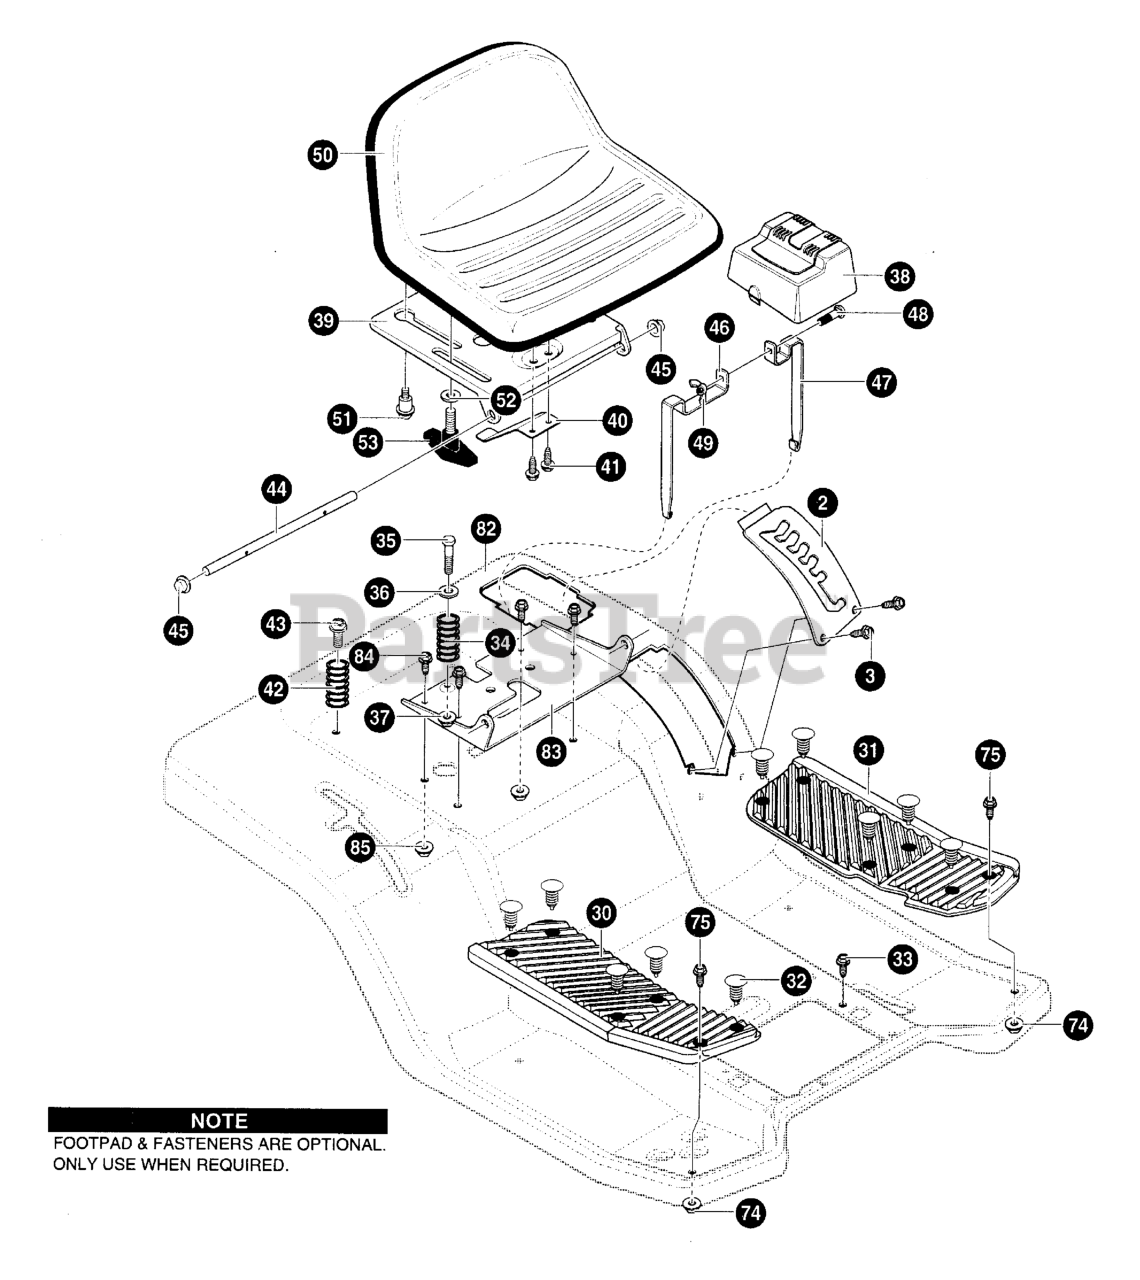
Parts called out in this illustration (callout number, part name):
2	PLATE, LIFT DETENT
3	SCREW, #12X.50 PHPNHTAP
30	FOOTREST PAD RH
31	FOOTREST PAD LH
32	RATCHET FASTENER
33	SCREW, 5/16-18 x .75 HHWATAP
34	SPRING, COMPRESSION 4.57LGX1.17
35	BOLT, SHOULDER 1/4-20
36	ZINC WASHER CUP
37	NUT, 1/4-20 CNTRLK
38	COVER, BATTERY
39	SUPPORT, SEAT
40	SPRING - LEAF
41	SCREW, 1/4-20X.50 WAHHTAP
42	SPRING, COMPRESSION 2.43LG 164X30
43	SCREW, 5/16-18 x 0.75 HHWATAP
44	ZINC HINGE SEAT PIVOT
45	NUT, PUSH CAP.375
46	BATTERY, BRACKET L.H.
47	BATTERY BRACKET R.H.
48	BOLT, 1/4-20X.63 CARR.
49	NUT, WING 1/4-20 14X79
51	BOLT, SHOULDER 5/16-18
52	WASHER, FLAT .344X.62X.06
53	BOLT, WING 5/16-18X.50
74	NUT, 5/16-18 HEXWDFLLK WHIZ
75	BOLT, 5/16-18X.7A5 CARR.
82	ASM., SEAT DECK PEDAL GEAR
83	BRACKET, PIVOT SEAT
84	SCREW, 5/16-18 x 0.75 HHWATAP
85	NUT, 5/16-18 WDFLLK
